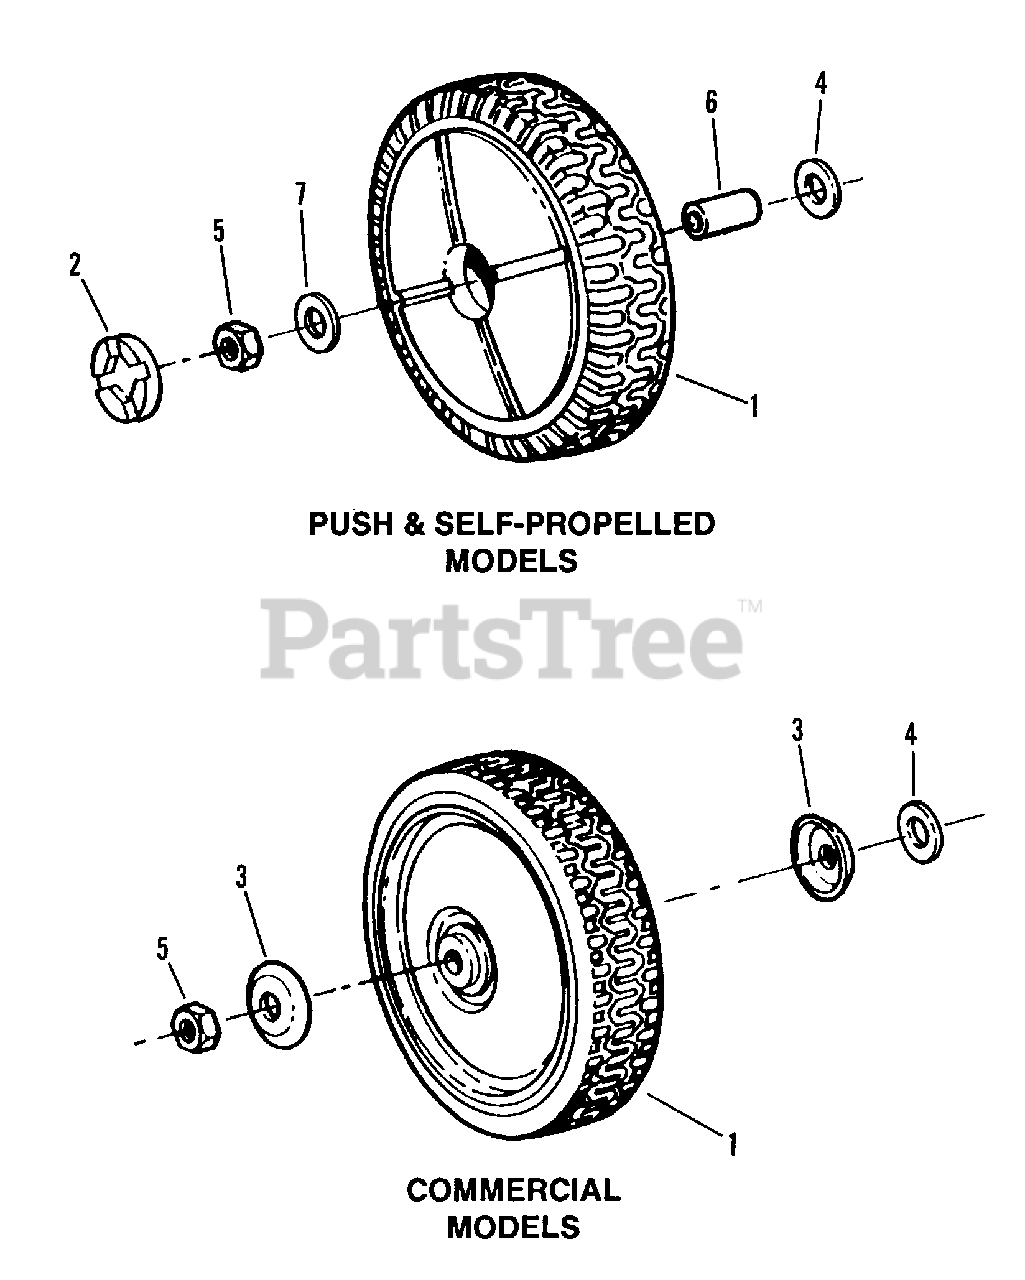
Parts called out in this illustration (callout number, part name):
1	WHEEL, 7 x 1.75 Plastic Rim (Standard)
2	PLUG, Wheel
3	HUB-CAP
4	WASHER, 7/16 Flat
5	NUT, 7/16-20 Hex Center Lock
6	BUSHING, Axle
7	WASHER, 7/16" ID x 1" OD SAE
